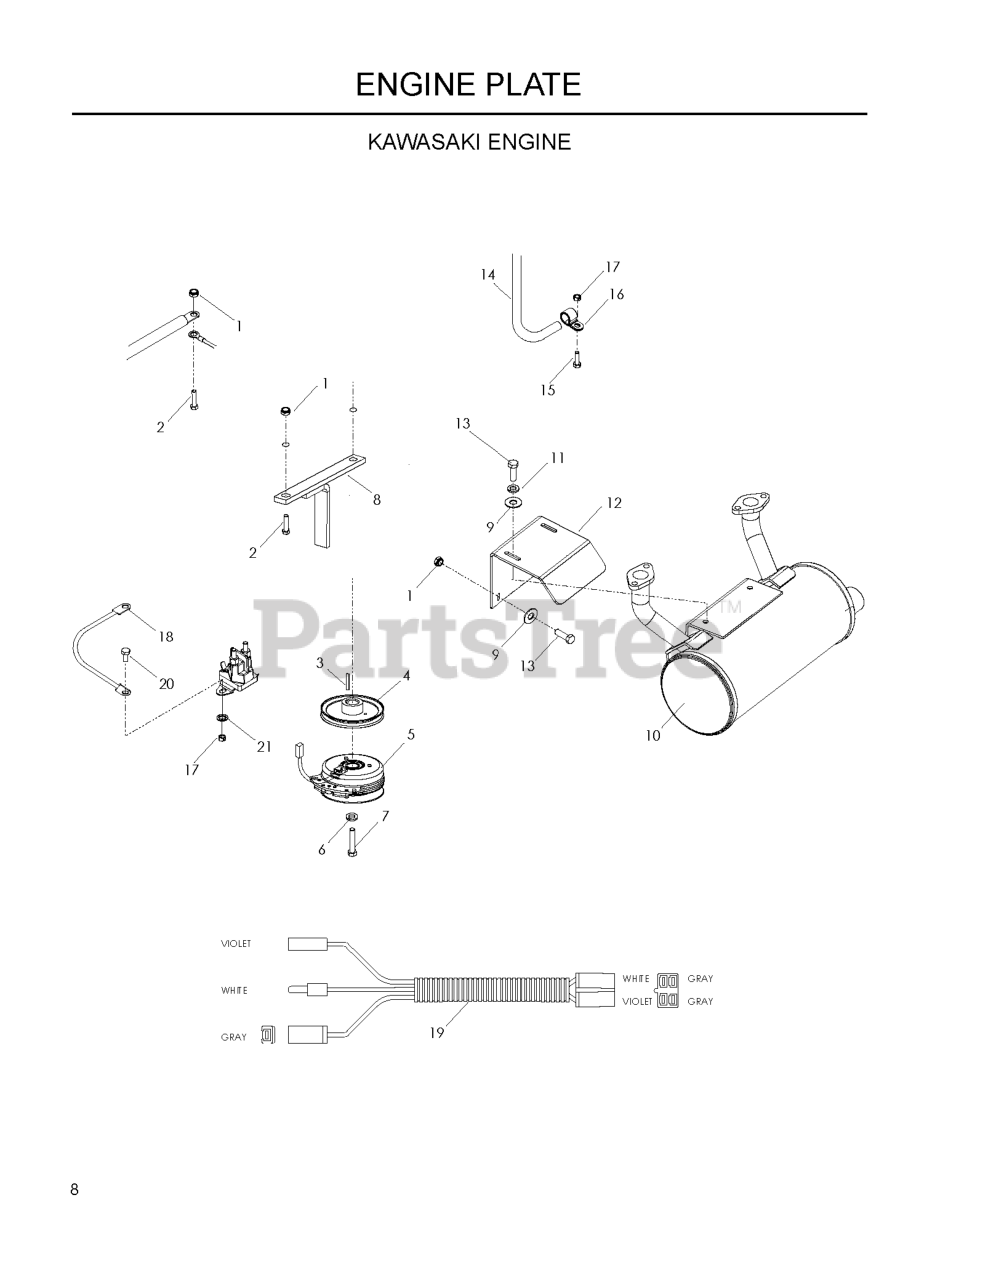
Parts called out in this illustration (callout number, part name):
1	NUT 5/16 NYLOC
2	HCS 5/16C X 1 3/4
3	KEY 1/4" SQ X 1 7/8"
5	ELECTRIC CLUTCH W/CABLE
6	WASHER 7/16 LOCK
7	BOLT 7/16F X 2 1/2
8	CLUTCH TIE DOWN
9	WASHER 5/16 FLAT
10	MUFFLER KAWASAKI GEN II
11	WASHER.LOCK.HVY.HLCL.SPR.5/16
12	MUFFLER BRACKET BLACK
13	HCS 5/16C X 1
14	OIL DRAIN HOSE
15	HCS 1/4C X 3/4 HCS
17	NUT 1/4C CENTER LOCK
18	GROUND WIRE (KAW)
19	KAW PIGTAIL
20	HCS 1/4C X 5/8
21	WASHER 1/4 INT TOOTH
